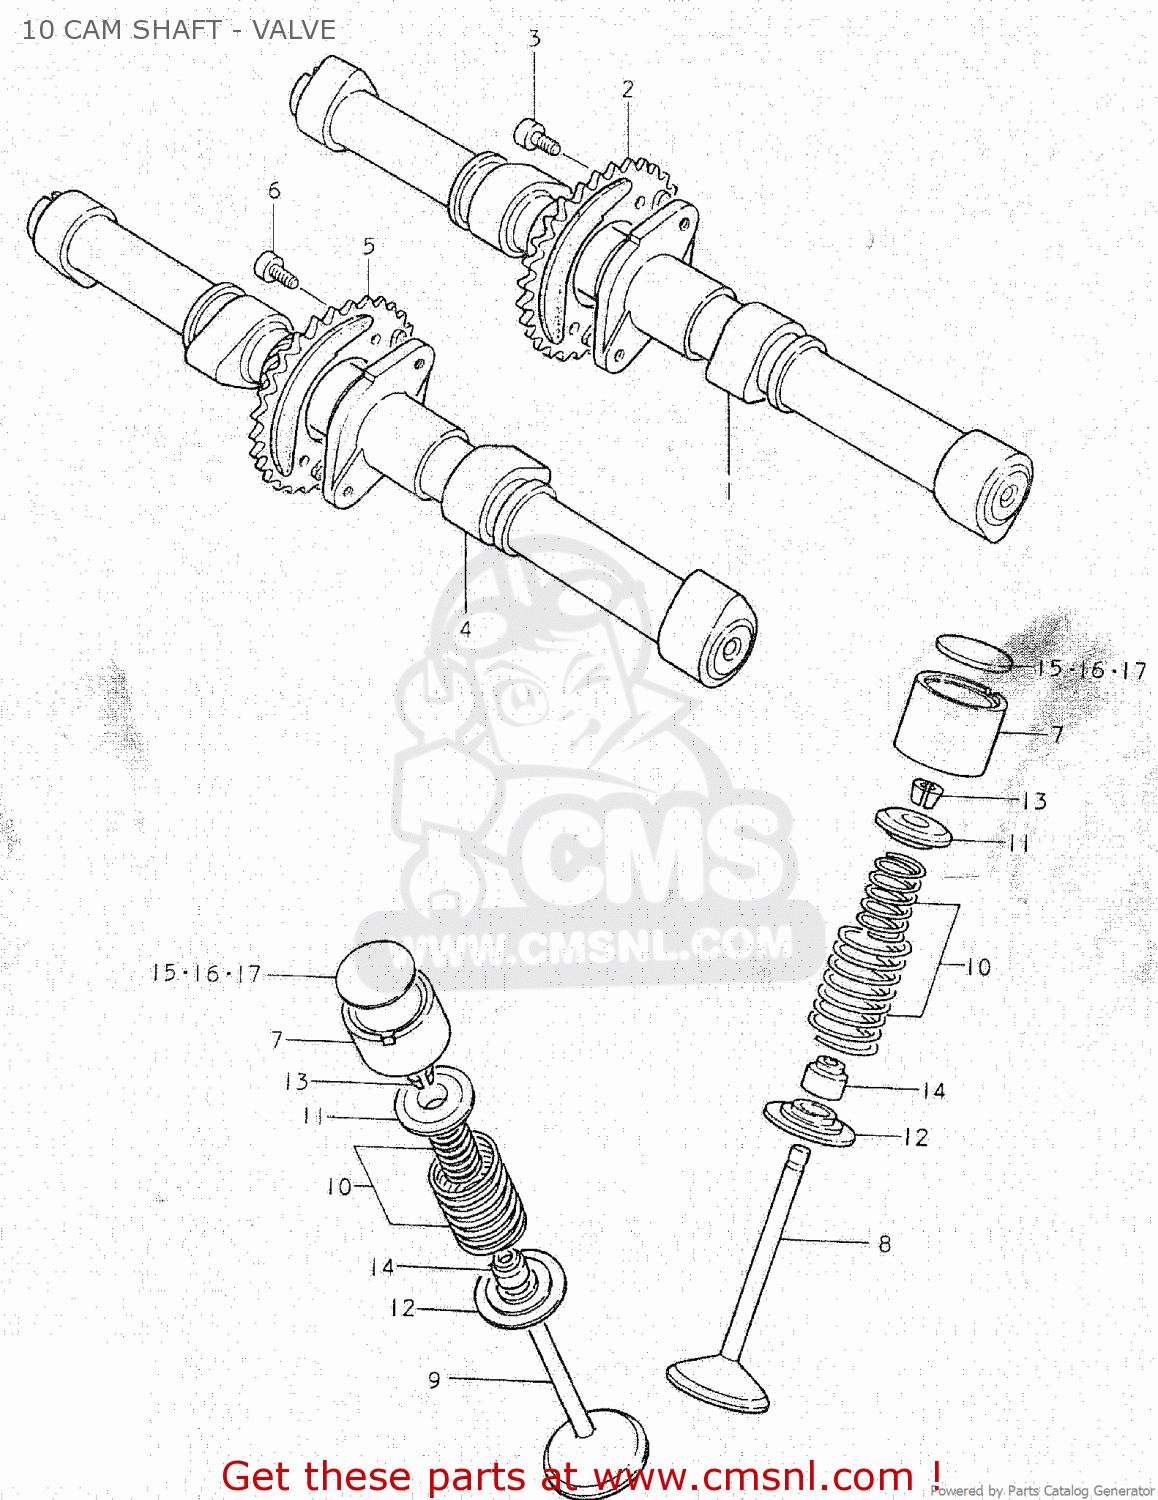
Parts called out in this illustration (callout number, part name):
1	CAMSHAFT
2	SPROCKET,CAMSHAFT
3	BOLT 6X11
4	CAMSHAFT,EXHAUST
5	SPROCKET,EXHAUST CAMSHAFT
6	BOLT 6X11
7	TAPPET
8	VALVE,INTAKE
9	VALVE,EXHAUST
10	SPRING SET,VALVE
11	RETAINER,VALVE SPRING
12	SEAT,VALVE SPRING
13	COTTER,VALVE
14	SEAL,OIL(7X14.4X9)
15	SHIM,TAPPET
16	SHIM,TAPPET
17	SHIM,TAPPET
